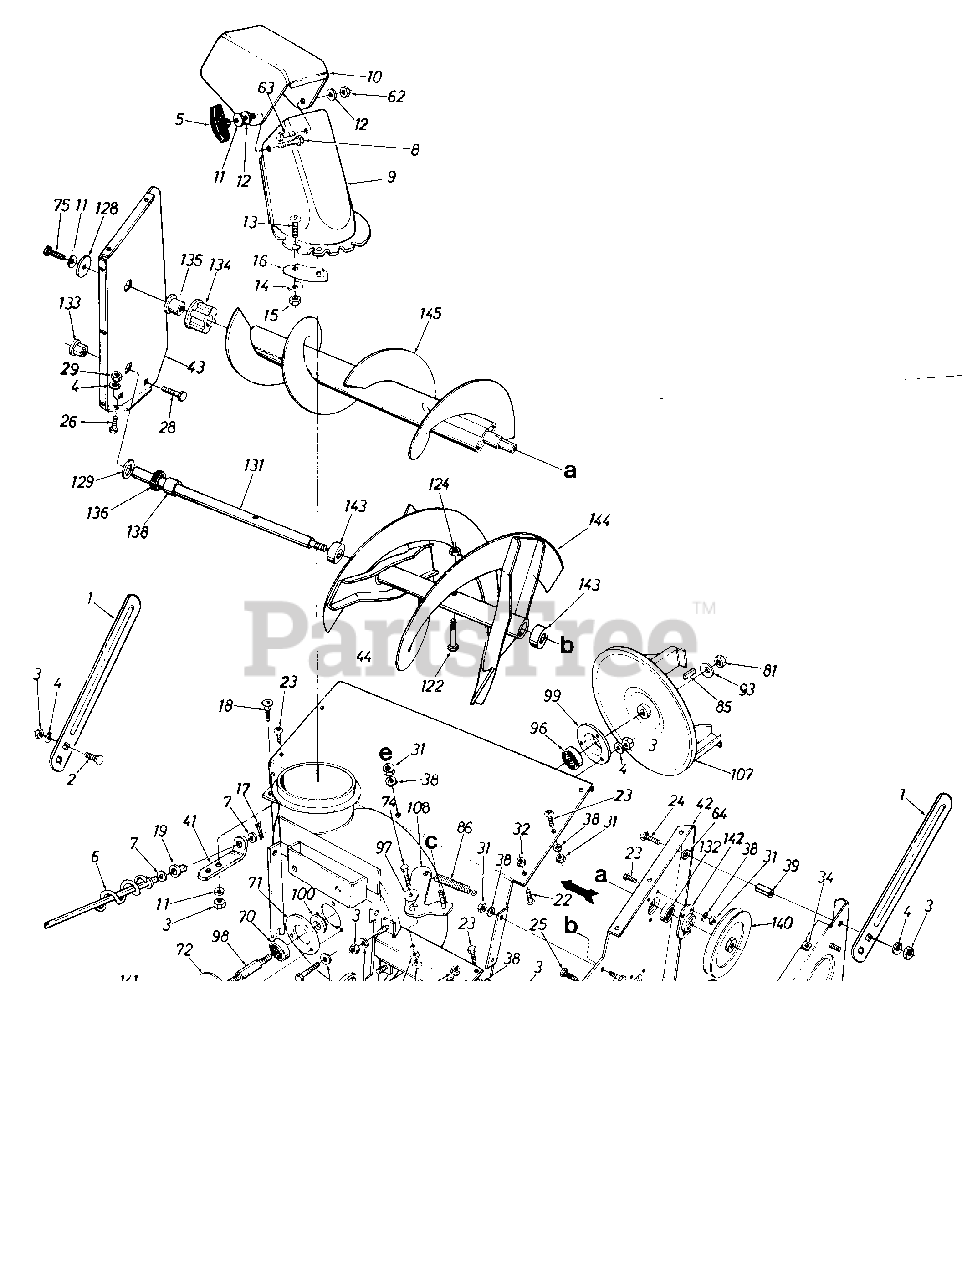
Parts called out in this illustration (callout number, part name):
1	Guide Blade
2	Carriage Bolt 5/16-18 x .62"
3	Hex Nut 5/16-18 Thd.
4	L-Wash. 5/16" I.D.
5	Hand Knob Ass'y.
6	Chute Crank Ass'y.
7	Fl-Wash. .385" I.D. x .62"
8	Carriage Bolt 5/16-18 x 1.0"
9	6" Dia. Lower Chute
10	6" Dia. Upper Chute
11	Bell-Wash. .345" I.D. x .88" O.D. x .06"
12	Fl-Wash. .344" I.D. x .125" O.D. x .125"
13	Truss Mach. Scr. 1/4-20 x .75" Lg.
14	Fl-Wash. 1/4" I.D.
15	Hex L-Nut 1/4-20 Thd.
16	Chute Flange Keeper
17	Cotter Pin
18	Carriage Bolt 5/16-18 x .75"
19	Bushing
20	Hex Self-Tap Scr. 5/16-24 x .5" Lg.
22	Truss Mach. Scr. 1/4-20 x .5"
23	Hex Bolt 1/4-20 x .5" Lg.
24	Carriage Bolt 5/16-18 x 1.75
25	Hex Bolt 3/8-16 x 2.0"
26	Hex Bolt 5/16-18 x .75" Lg.
27	Hex Self-Tap Scr. 1/4-20 x .38" Lg.
28	Carriage Bolt 3/8-16 x .62"
29	Hex Nut 5/16-24 Thd.
31	Hex Nut 1/4-20 Thd.
32	Hex Ins. L-Nut 1/4-20 Thd.
33	Hex Jam Nut 3/8-16 Thd.
34	Speed Clip
35	Bell-Wash. 3/8" I.D.
38	L-Wash. 1/4" I.D.
39	Spacer .375" I.D. x 1" Lg.
40	Slide Shoe
42	Spiral Housing Plate R.H.
43	Spiral Housing Plate L.H.
44	24" Spiral Hsg. Ass'y.
54	V-Channel
55	Support Bracket
56	Side Cover Ass'y.
60	Belt Cover 6.42"
63	Truss Mach. Scr. 5/16-18 x .75"
64	Push Speed Nut
70	Ball Bearing
71	Spindle Reinforcement Plate
72	Open Brg. Housing
73	Hex Bolt 3/8-24 x 1.5" Lg.
74	Hex Bolt 3/8-24 x 1.25" Lg.
75	Hex Bolt 5/16-18 x 1" Lg. (Gr. 5)
78	Hex Ins. L-Nut 3/8-24
79	Hex Nut 3/8-24 Thd.
81	Hex Jam Nut 5/8-18 Thd.
83	Hex L-Nut 5/8-18 Thd.
84	Sq. Key 3/16" x .75"
85	Sq. Key 3/16" x 1.5"
86	Ext. Spring 3/4" O.D. x 4" Lg.
90	Fl-Wash. .635" I.D.
91	L-Wash. 3/8" I.D.
93	Bell-Wash. .630" I.D.
95	Shld Bolt .50" Dia. x 2.11" Lg.
96	Ball Bearing
97	Shld. Spacer .625 I.D.
98	Fan Spindle
99	Bearing Hsg. Ass'y.
100	Spacer.790" I.D.
103	5/8 V-Pulley 7.5" O.D.
104	V-Idler Pulley 3.5" O.D.
107	11" Dia. Blower Fan Ass'y.
108	Idler Bracket Ass'y.
109	Fl-Wash. .40" I.D.
122	Shear Bolt 5/16-18 x 1.5"
124	Hex Ins. L-Nut 5/16-18 Thd.
128	Flat Washer .32" I.D.
129	Fl-Wash. .76" I.D.
131	Spindle Shaft
132	Ball Brg. .62" I.D.
133	Hex Flange Brg.
134	Tubing Support Brg.
135	Shaft Pin
136	Spacer 1.25" I.D. x 1.5"
137	V-Belt
138	Spacer
139	1/2 V-Pulley 9" O.D.
140	1/2 V-Pulley 5.5" O.D.
141	1/2 V-Pulley 2.75"
142	Bearing Housing
143	Sleeve Brg. .75" I.D.
144	10" Spiral Ass'y. R.H.
145	24" Auger Ass'y.
